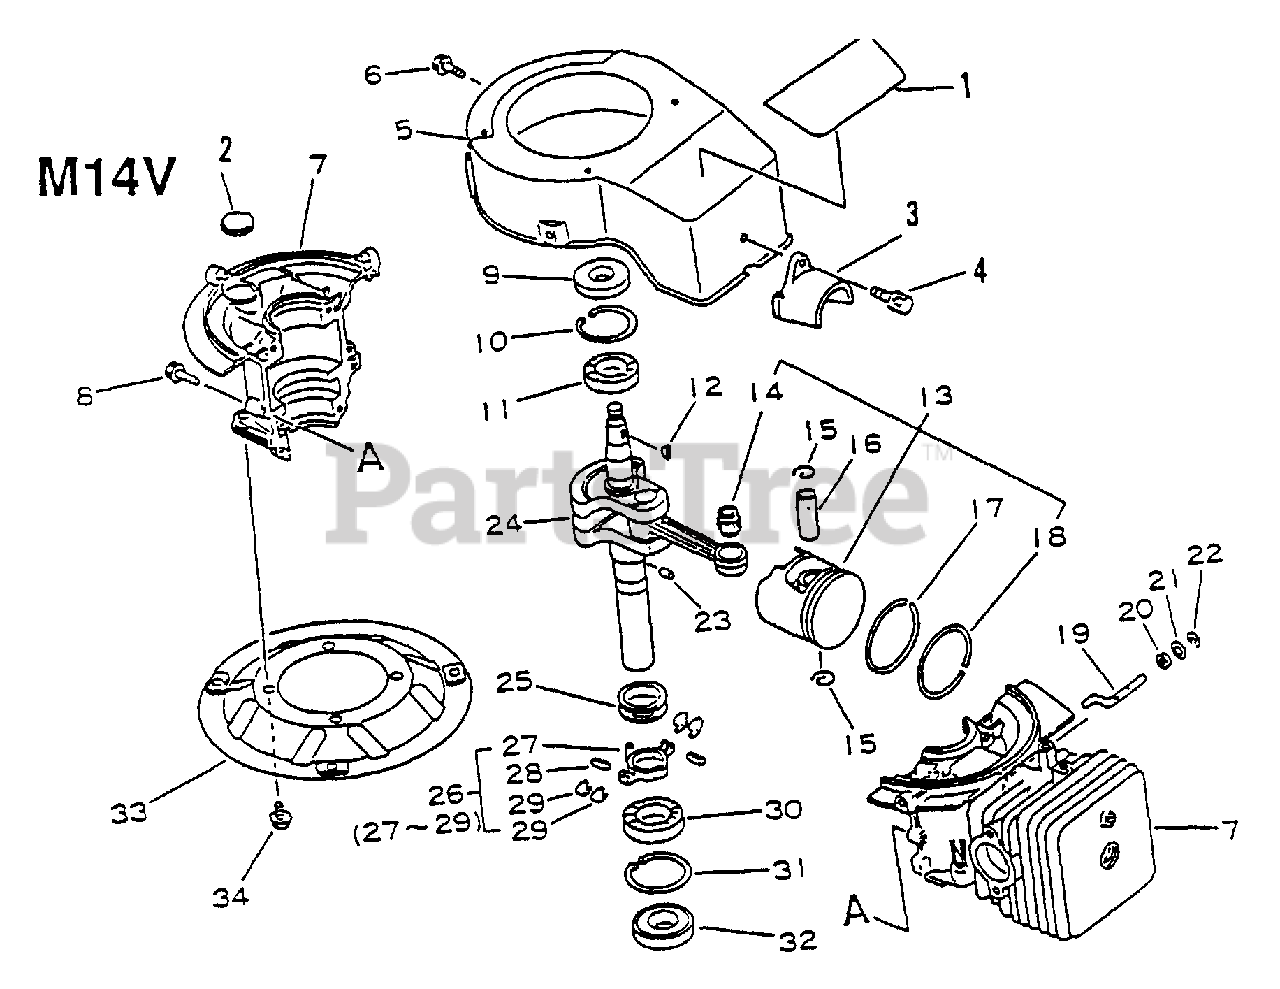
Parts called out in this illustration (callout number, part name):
1	LABEL - ECHO
2	PLUG
3	PLUG, GUARD
4	BOLT - 6X16
5	CASE, FAN
6	BOLT - 6X10
7	CRANKCASE KIT
8	BOLT - 6X25
9	SEAL, OIL
10	RING, RETAINING - 47
11	BEARING, BALL - 6203C3
12	KEY - 3X14
13	PISTON KIT
14	BEARING, NEEDLE
15	RING, RETAINING
16	PIN, PISTON
17	RING, PISTON
18	RING, PISTON
19	SHAFT, GOVERNOR
20	SEAL, OIL
22	RING, RETAINING - 4
23	PIN
24	CRANKSHAFT ASSY
25	SEAL, OIL
26	WEIGHT KIT
27	HOLDER
28	PIN - SPRING -- 3X10
29	WEIGHT, GOVERNOR
30	BEARING, BALL
31	RING, RETAINING - 52
32	SEAL, OIL
33	BRACKET, ENGINE
34	BOLT - 8X16
